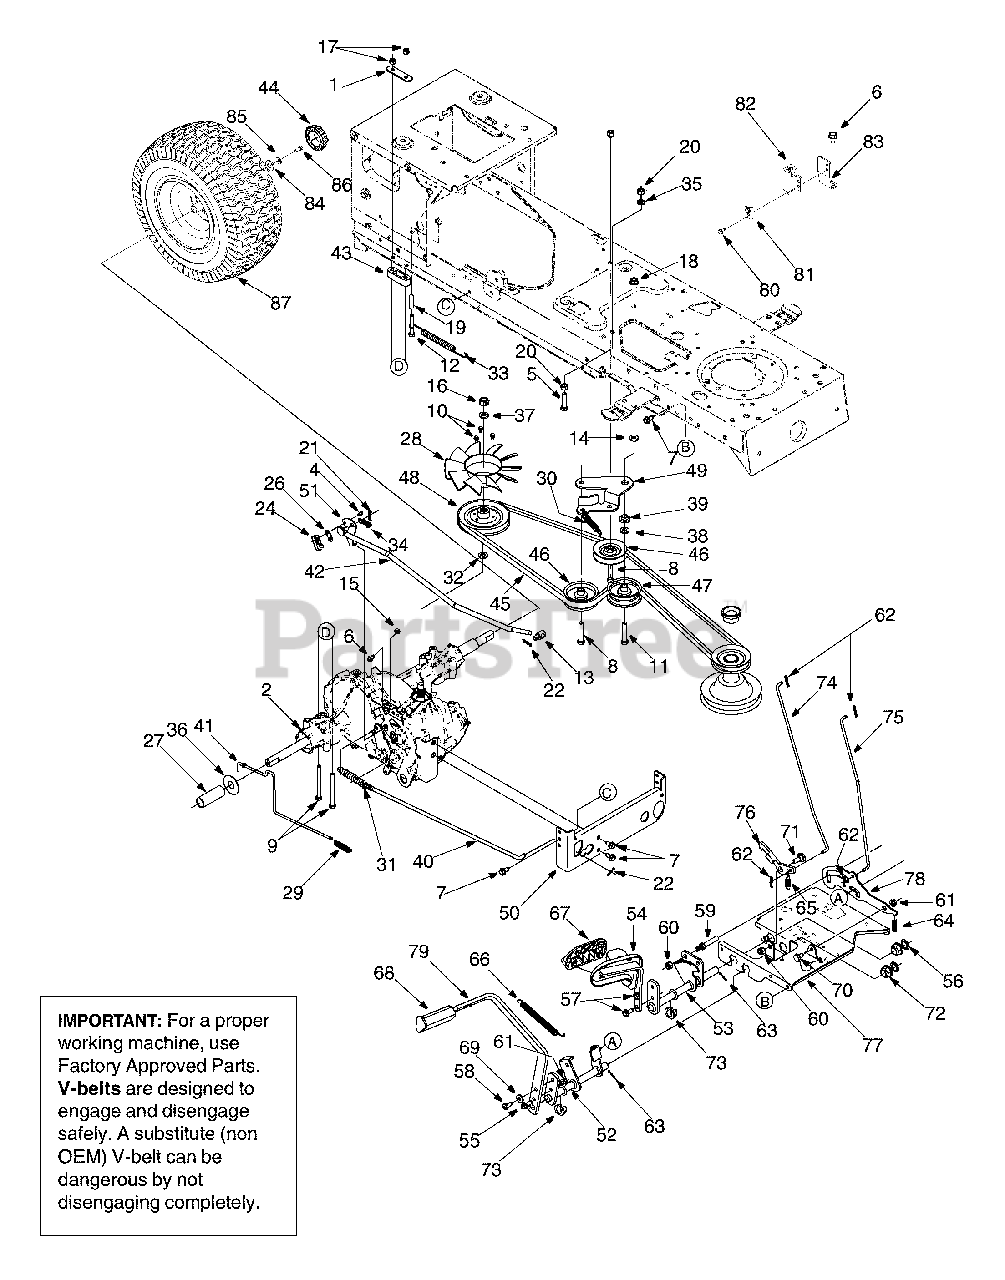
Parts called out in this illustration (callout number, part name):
2	Hydrostatic Transmission
4	AB Screw #8-18 x 0.5
5	Hex Bolt 3/8-16 x 1.5
6	TT Screw 1/4-20 x 0.5
7	AB Screw 5/16-12 x 0.75
8	TT Sems Screw 3/8-16 x 1.250
9	Hex Bolt 5/16-18 x 3.5
10	Carriage Screw
11	Hex Bolt 3/8-16 x 2.25
12	Screw, 1/4-20 x 1.250
13	Ferrule
14	Flat Washer,.38 x 1.38 x.125
15	Hex Lock Nut 1/4-20
16	Hex Nut, 1/2-20
17	Flange Lock Nut, 5/16-18
18	Flanged Lock Nut 3/8-16
19	Spacer,.260 x.372 x 1.030 Lg
20	Hex Nut 3/8-16
21	Cotter Pin
22	Cotter Pin
24	Switch
26	Insulator Nut Plate
27	Sleve, 0.758 x 0.821 x 1.5
28	Blade Fan
29	Extension Spring
30	Extension Spring
31	Extension Spring
32	Wire Ring
33	Extension Spring
34	Extension Spring
35	Lock Washer
36	Flat Washer
37	Lock Washer
38	Flat Washer
39	Shoulder Spacer
40	Brake Rod
41	Bypass Rod
42	Control Rod
43	Transaxle Spacer
44	Hub Cap
45	V Belt, A x 78" Lg
46	Idler Pulley
47	Flat Idler Pulley
48	Input Pulley
55	TT Screw 5/16-18 x 0.875
56	Flat Washer,.64 x 1.24 x.06
57	LD Screw 5/16-18 x 0.75
58	TT Screw 5/16-18 x 0.75
60	Flange Lock Nut, 3/8-16
61	Flange Lock Nut, 5/16-18
62	Cotter Pin
63	Cotter Pin
64	Compression Spring
65	Extension Spring
66	Extension Spring
67	Control Pedal
68	Brake Control Pedal
69	Flat Washer
70	Shoulder Screw
71	Shoulder Screw
72	Hex Flange Bearing
73	Hex Flange Bearing
74	Brake Lock Control Rod
75	Cruise Control Rod
76	Cruise Latch
78	Lockout Bracket
81	Switch Plate
82	Interlock Switch
85	Bell Washer,.340 x.872 x.060
86	Screw, 5/16-24 x.750
